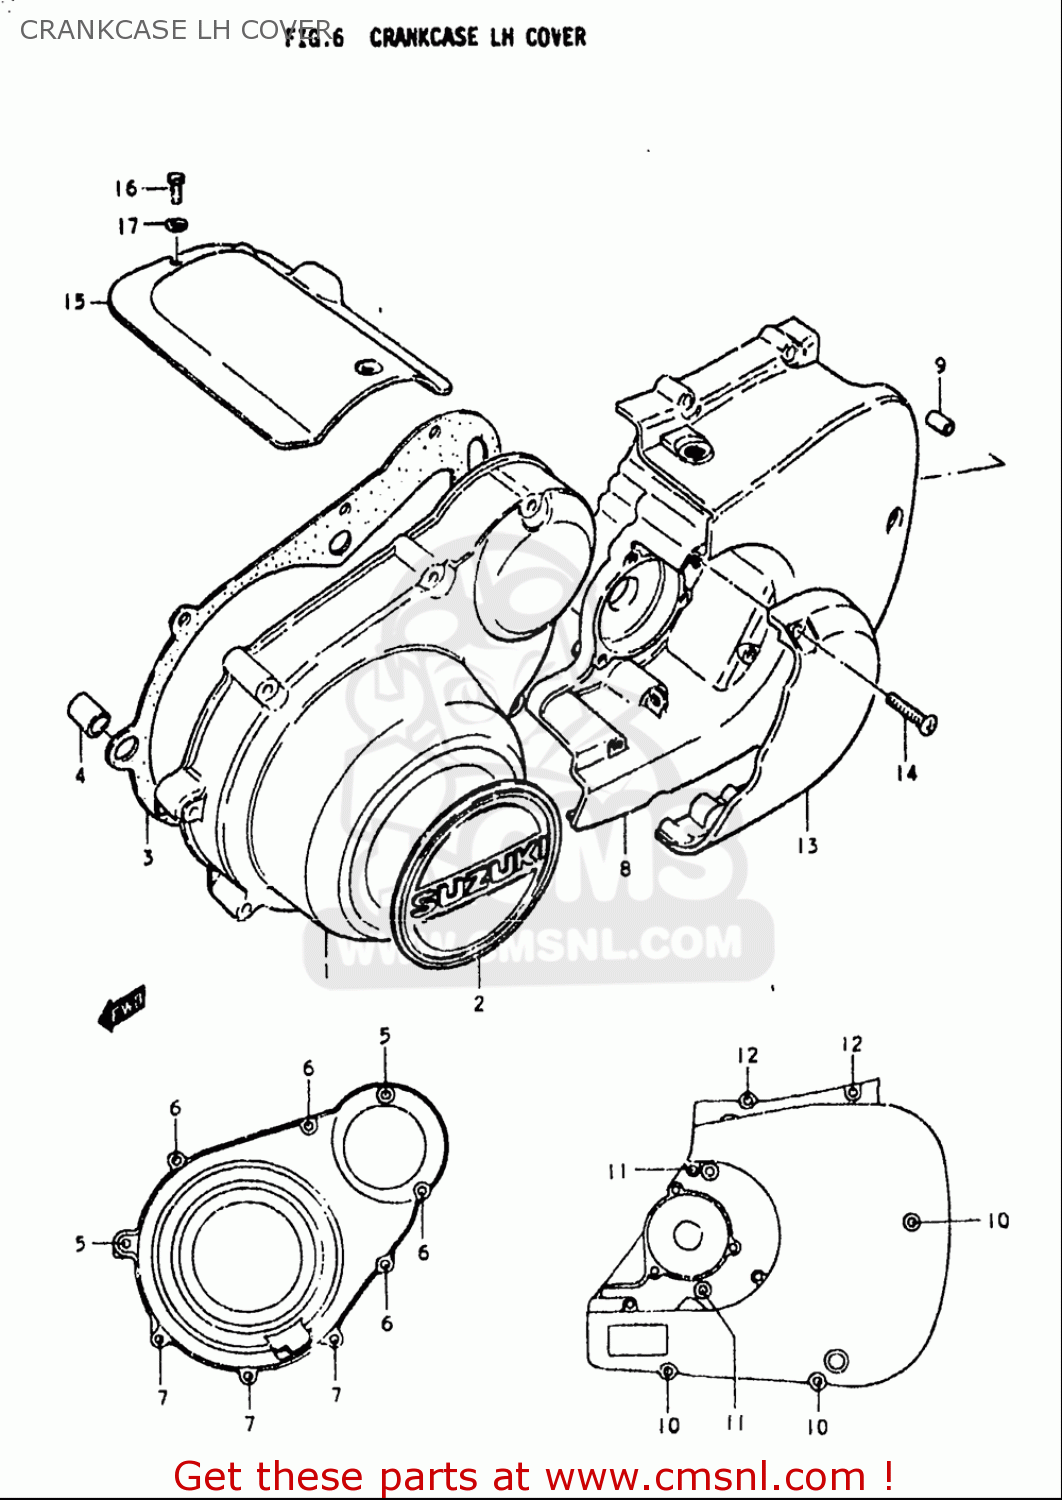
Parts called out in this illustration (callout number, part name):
1	COVER,MAGNETO
2	EMBLEM,MAGNETO COVER
3	GASKET,MAGNETO COVER (NAS)
4	PIN
5	SCREW
6	SCREW
7	SCREW
9	PIN
10	SCREW
11	SCREW
12	SCREW
14	SCREW
15	COVER,STARTER MOTOR
16	BOLT
17	WASHER
